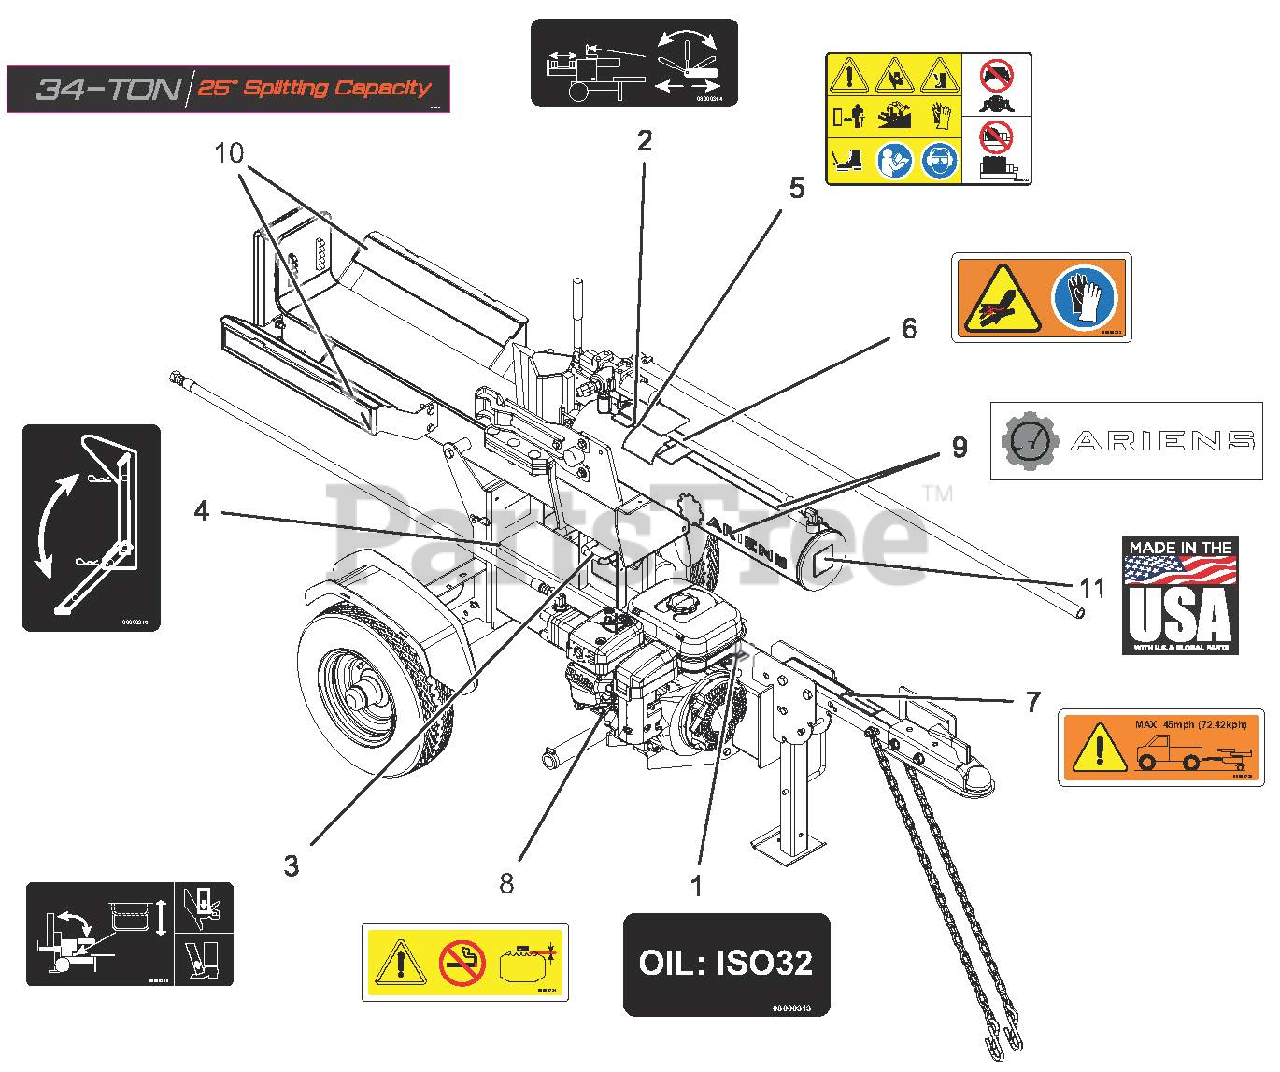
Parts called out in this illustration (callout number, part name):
1	DECAL, LOG SPLITTER-HYD OIL
2	DECAL, LOG SPLITTER-RAM OP
3	DECAL, LOG SPLITTER-TILT OP
4	DECAL, LOG SPLITTER-REAR STAND
5	DECAL,DANGER LOG SPLITTER
6	DECAL,HYD WARNING
7	DECAL,TOWING
8	DECAL,FUEL WARNING
9	DECAL-ARIENS-CYLINDER
10	DECAL-CRADLE-34 TON
11	DECAL, MADE IN USA
